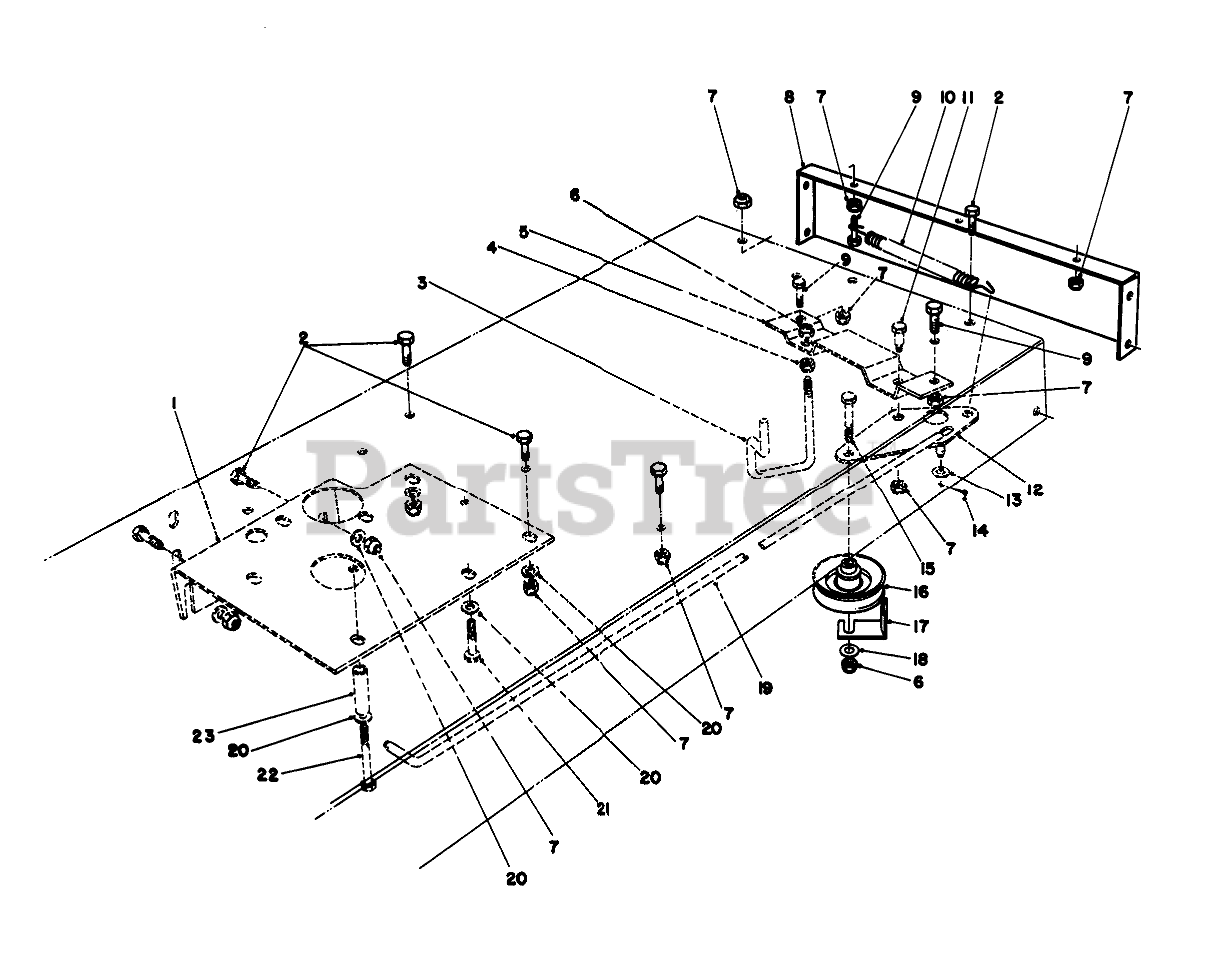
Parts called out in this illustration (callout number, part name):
1	REINF PLATE R
2	SCREW-HH
3	BELT GUIDE
4	NUT-LOCK, SIDE
5	TRACT SUPP BRKT B
6	NUT-LOCK, CONE
7	NUT-LOCK, NI
8	Frame-Rear
9	SCREW-HH
10	TRACTION SPRING
11	BOLT-SHOULDER
12	TRACTION PIVOT BRKT
13	WASHER-FLAT
14	PIN-COTTER
15	SCREW-HH
16	PULLEY-IDLER
17	RETAINER-BELT
18	WASHER-FLAT
19	Rod-Traction
20	WASHER-PLAIN
21	Screw-HH
22	SCREW-HH
23	OUTER TUBE SPACER
